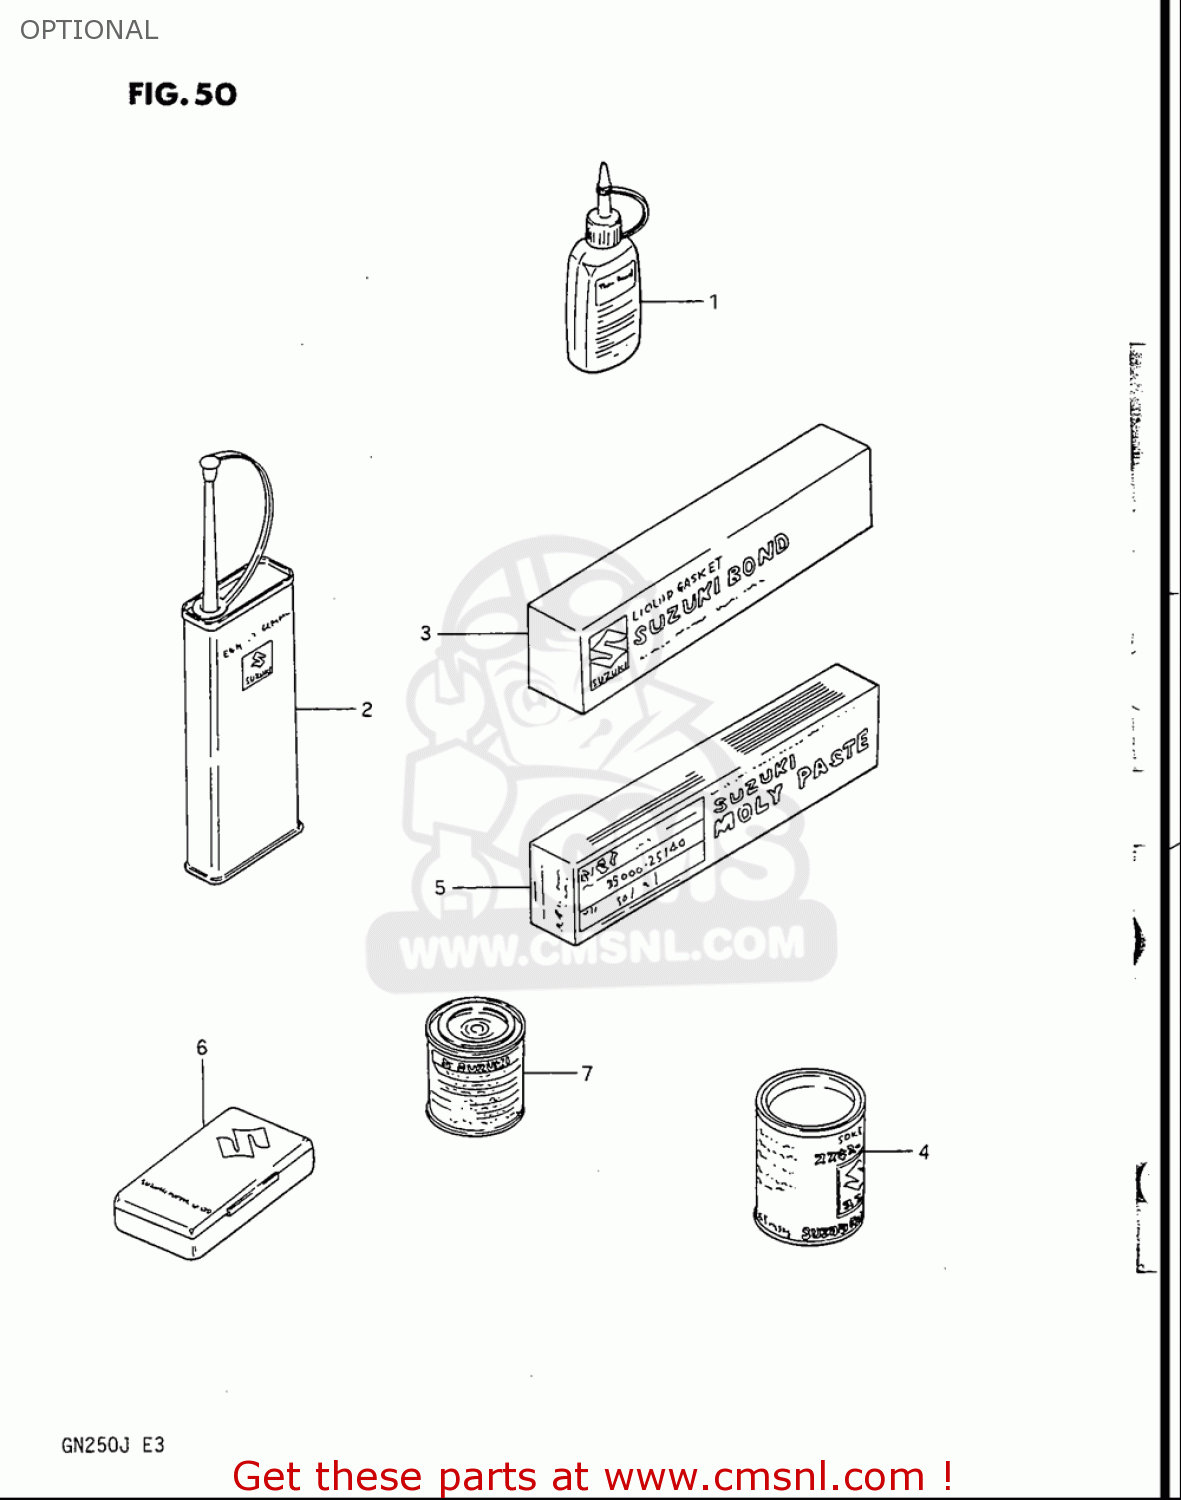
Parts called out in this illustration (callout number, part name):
1	THREAD LOCK NO.1342
2	THREAD LOCK NO.1401 CLEAR 200G
3	LIQUID GASKET 1
4	GREASE(C)EP2 LITHIUM 150G
5	SUZUKI MOLY PASTE
